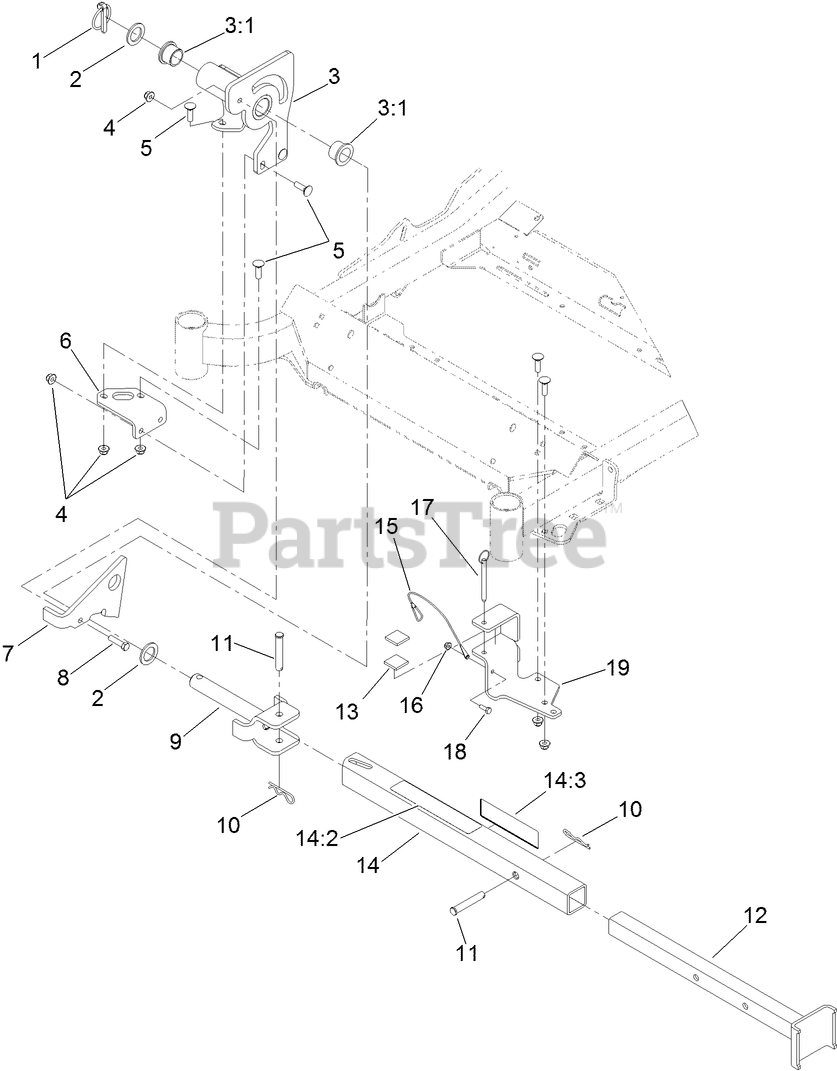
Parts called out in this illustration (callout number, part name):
1	PIN-LYNCH
2	WASHER-THRUST
3	Z STAND PIVOT ASM
3:1	BUSHING
4	NUT-HF, NI
5	BOLT-CARR
6	BRACKET-MOUNT, PIVOT
7	BRACKET-LATCH
8	SCREW-HH
9	PIN-PIVOT
10	PIN-HAIR
11	PIN-CLEVIS
12	TUBE-INNER
13	CUSHION-RUBBER
14	OUTER TUBE ASM
14:2	DECAL-Z STAND
14:3	DECAL-WARNING
15	LANYARD-NYLON
16	NUT-HF
17	PIN-HITCH, COTTERLESS
18	SCREW-HH
19	CRADLE-Z STAND
